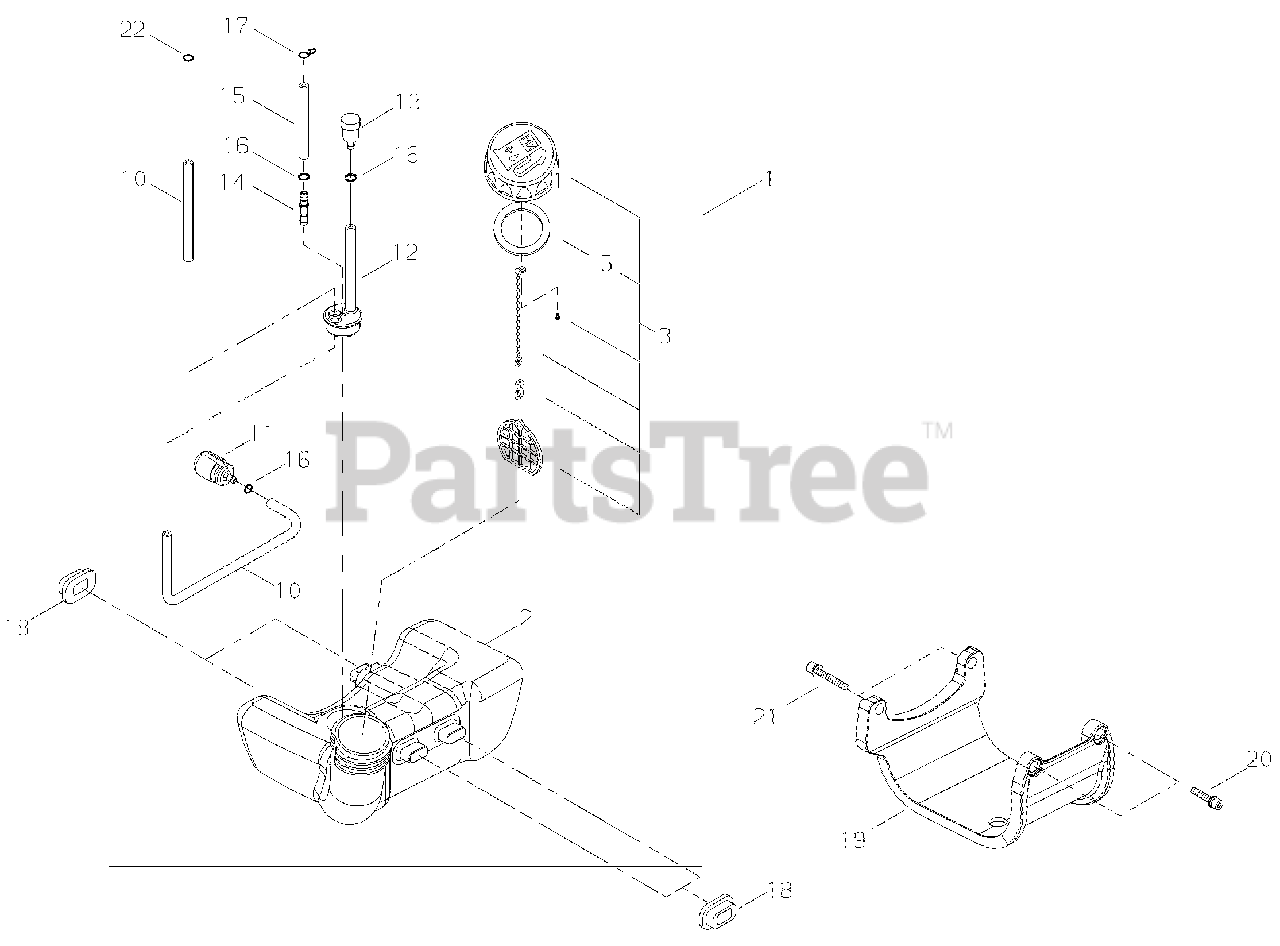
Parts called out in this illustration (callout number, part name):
1	FUEL TANK ASSY
2	TANK, FUEL
3	CAP ASSY
5	GASKET, CAP
10	PIPE - FUEL
11	FILTER, FUEL
12	PIPE ASSY
13	VENT, FUEL TANK
14	CONNECTOR, PIPE
15	PIPE - RETURN
16	RING, RETAINING - 6
17	CLIP - SPRING
18	CUSHION, FUEL TANK
19	GUARD, FUEL TANK
20	SCREW - 5X18
21	SCREW - 5X40
22	RING, RETAINING - 6
